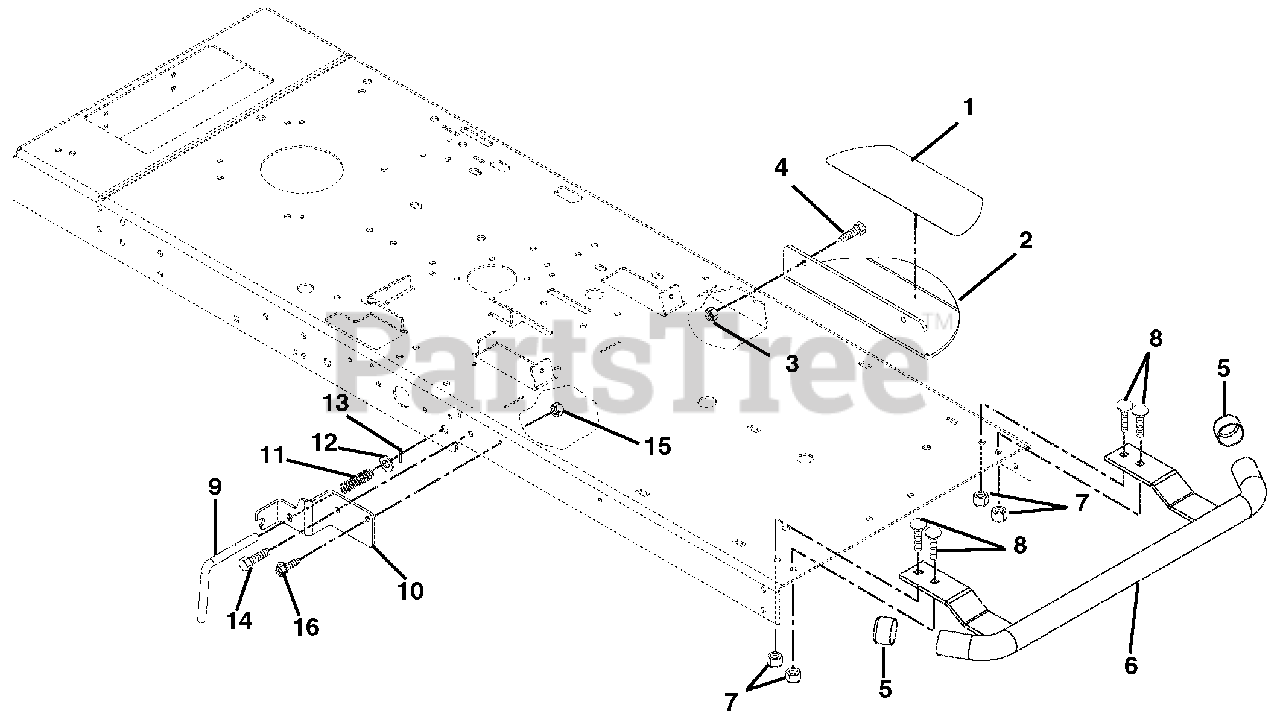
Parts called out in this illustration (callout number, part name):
1	Non-Skid Cover
2	Bracket, Step
3	Nut-Locking-Top-Flange .31-18
4	Screw-Tapping .31-18 x .88 Hex Washer Head
5	Cap-Sleeve
6	Weldment-Bumper
7	Nut-Locking-Top-Flange .38-16
8	Bolt-Round Head Square Neck .375-16 x 1.00 Grade 5
9	Pin-Index
10	Bracket-Stop
11	Spring-Compression
12	Washer-Flat-Steel .531 x 1.06 x .095
13	Pin-Roll .156 x 1.00
14	Bolt-Screw Hex Flanged Whiz Lock Head .38-16 x .75
15	Nut-Locking-Top-Flange .38-16
16	Screw-Tapping .31-18 x .75 Hex Washer Head
